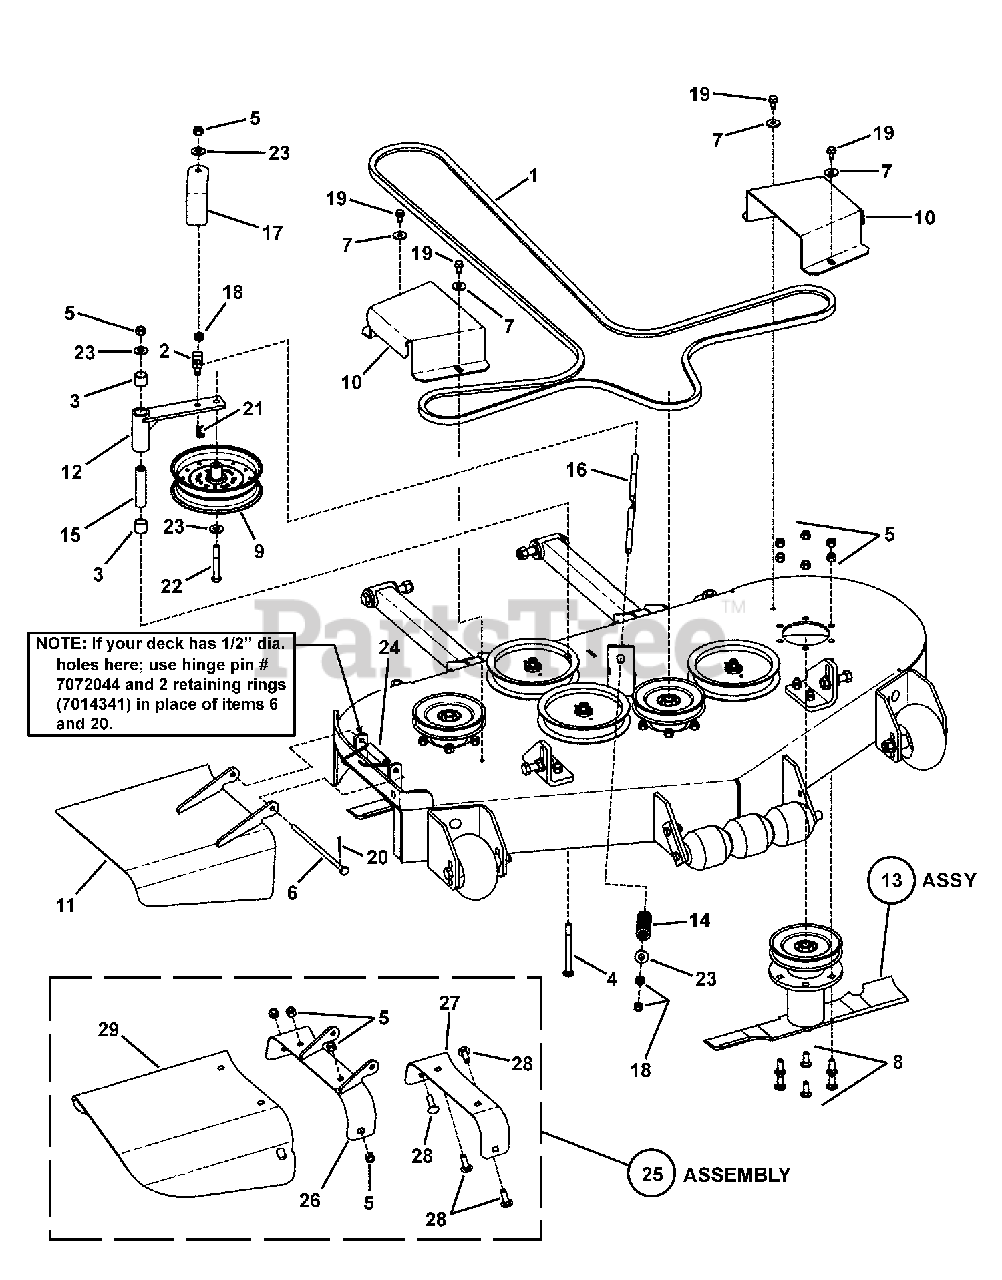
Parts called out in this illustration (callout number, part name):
1	* BELT, HB Sect. 150.00" nom., HD
2	SWIVEL, 3/8" w/thru hole
3	BUSHING, SLEEVE, 3/4 ID, GV3031224
4	BOLT, 3/8-16 x 4-1/2" Square Neck Carriage, GR 5
5	NUT, 3/8-16 HEX NYLON LOCK
6	PIN, Chute Hinge
7	WASHER, .34 x 1.0 x .09 Flat
8	BOLT, 3/8-16 x 1" Square Neck Carriage, GR 5
9	* PULLEY, 6" O.D. Idler (assembly)
10	BELT GUARD
11	WELDMENT, 48" Discharge Chute
12	WELDMENT, Deck Idler Arm
13	ASSEMBLY, 48" Spindle
14	SPRING, CVT Brake
15	IDLER BOSS
16	ROD, Tensioner (3/8-16 threads)
17	* BELT GUIDE
18	NUT, 3/8-16 Hex, GR 5 or B
19	SCREW, 5/16-18 x 5/8" Hex Washer Self-Tap
20	PIN, 3/32 x 1" Cotter
21	HAIR PIN, 3/32 x 1-1/2"
22	BOLT, 3/8-16 X 2-3/4" GD5 CZ
23	WASHER, 3/8" USS
24	SPRING, Chute
25	ASSY, Discharge Chute
26	WELDMENT, 48" Chute
27	DEFLECTOR, Bottom
28	BOLT, 3/8-16 x 1-1/4" Square Neck Carriage, GR 5
29	CHUTE, Rubber 48"
